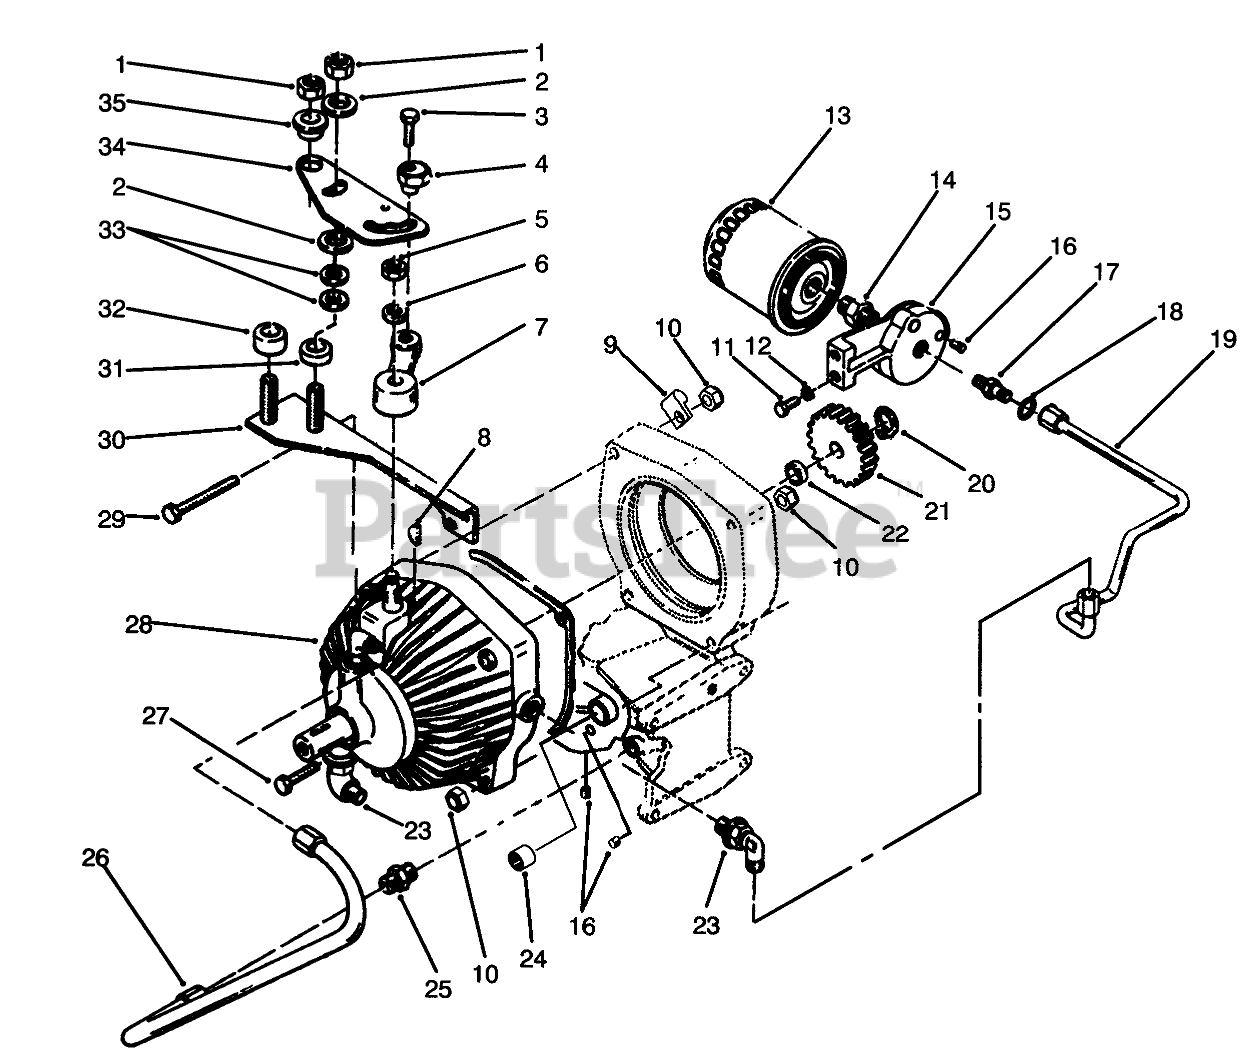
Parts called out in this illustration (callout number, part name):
2	FRICTION WASHER
3	Bolt
5	NUT-LOCK, NI
6	WASHER-FLAT
7	ARM-SPEED CONTROLB
8	KEY-WOODRUFF
9	CLIP
10	NUT-LOCK, NI
11	SCREW-HH
12	WASHER-LOCK
13	OIL FILTER ASM
14	FITTING
15	BASE-FILTER
17	FITTING
18	0-Ring
19	ASS'Y-TUBE FILTER
20	RING-SNAP, EXTERNAL
21	GEAR 20 TEETH DRIVE
22	SPACER GEAR
23	ELBOW
24	BEARING-NEEDLE
25	FITTING-TUBE
26	ASSY-TUBE SUCTION
27	Bolt
28	Pump & Motor
29	SCREW-HH
30	ASSY-PLATE B
31	SPACER-FRICTION
32	SPACER-PIVOT
33	WASHER-SPRING DISC
34	ASM-REAR LIFT R
35	CAM-SPACER
